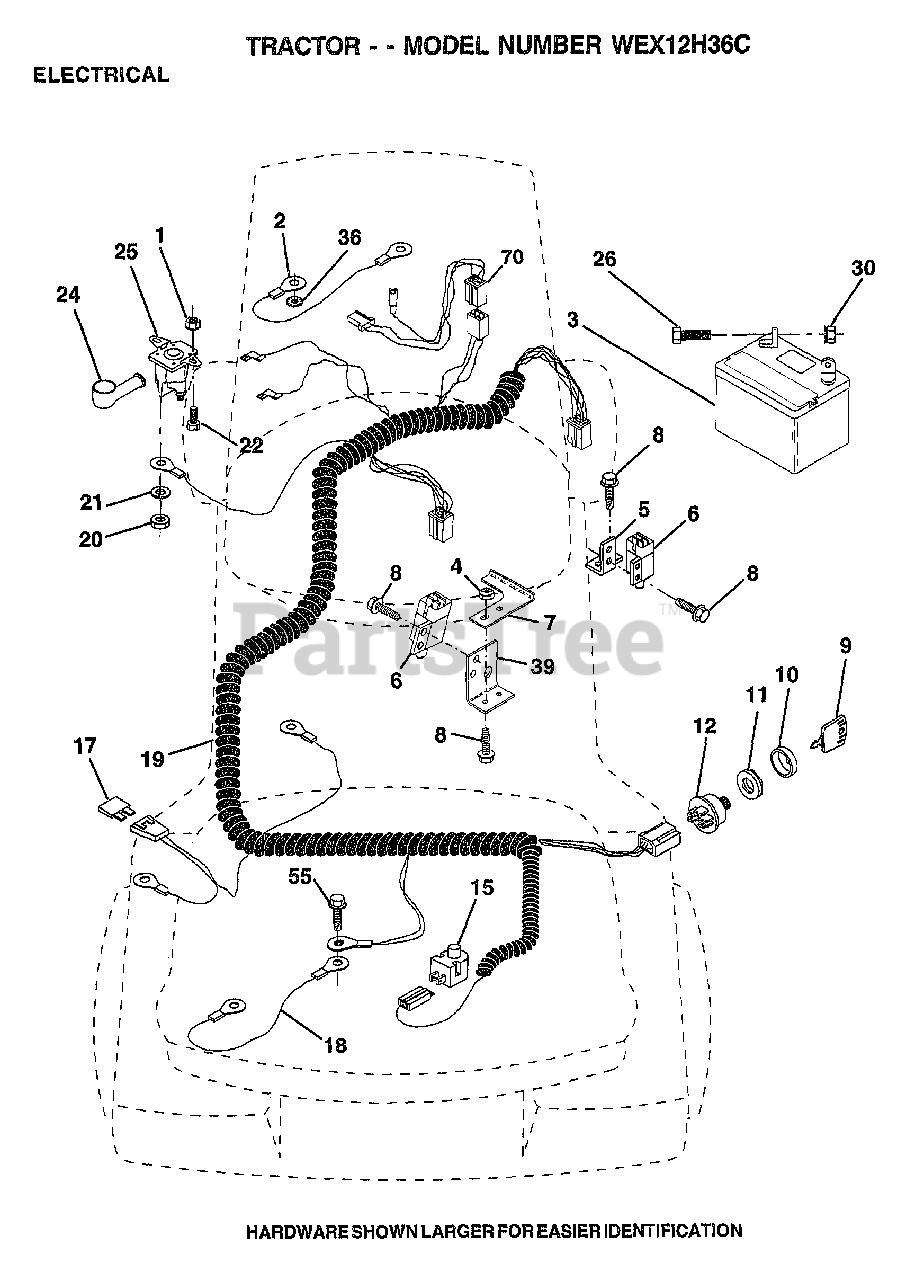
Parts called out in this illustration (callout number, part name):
1	NUT HXKEP 1/4X20
2	CABLE ASM.
4	LOCKNUT
5	BRACKET LT
6	SWITCH INTERLOCKT
7	KEEPER.ACTUAT.LR.
8	SCREW
9	KEY MLD GEN DELTA
10	COVER KEY SWITCH
12	SWITCH.IGNITION
15	SWITCH SEAT
17	FUSE.15 AMP
18	CABLE ASSY
19	HARNESS, IGNITION
20	NUT
22	BOLT HXHD FIN
26	BOLT LT
30	NUT
36	LOCKWASHER
39	BRACKET SWT CLUTC
55	SCREW LT
70	HARNESS ENG
